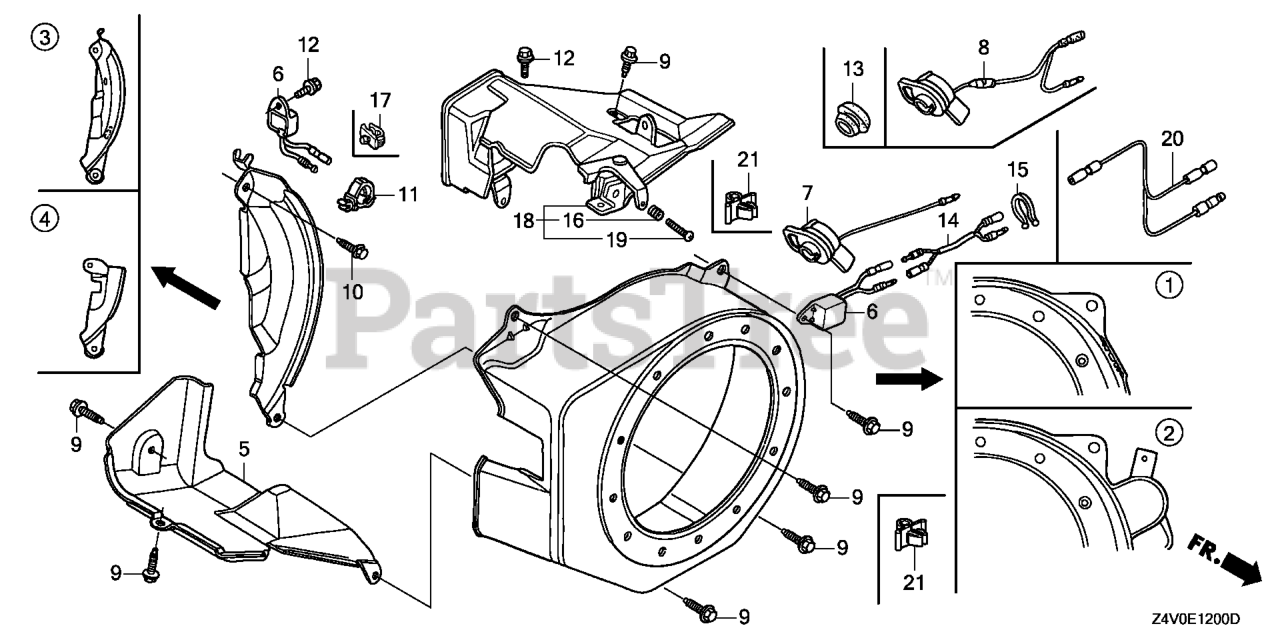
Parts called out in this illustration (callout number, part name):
2	COVER, FAN *R280* (STARTER MOTOR) (POWER RED)
4	PLATE, SIDE (STARTER MOTOR)
5	SHROUD
9	BOLT, FLANGE (6X12) (CT200)
